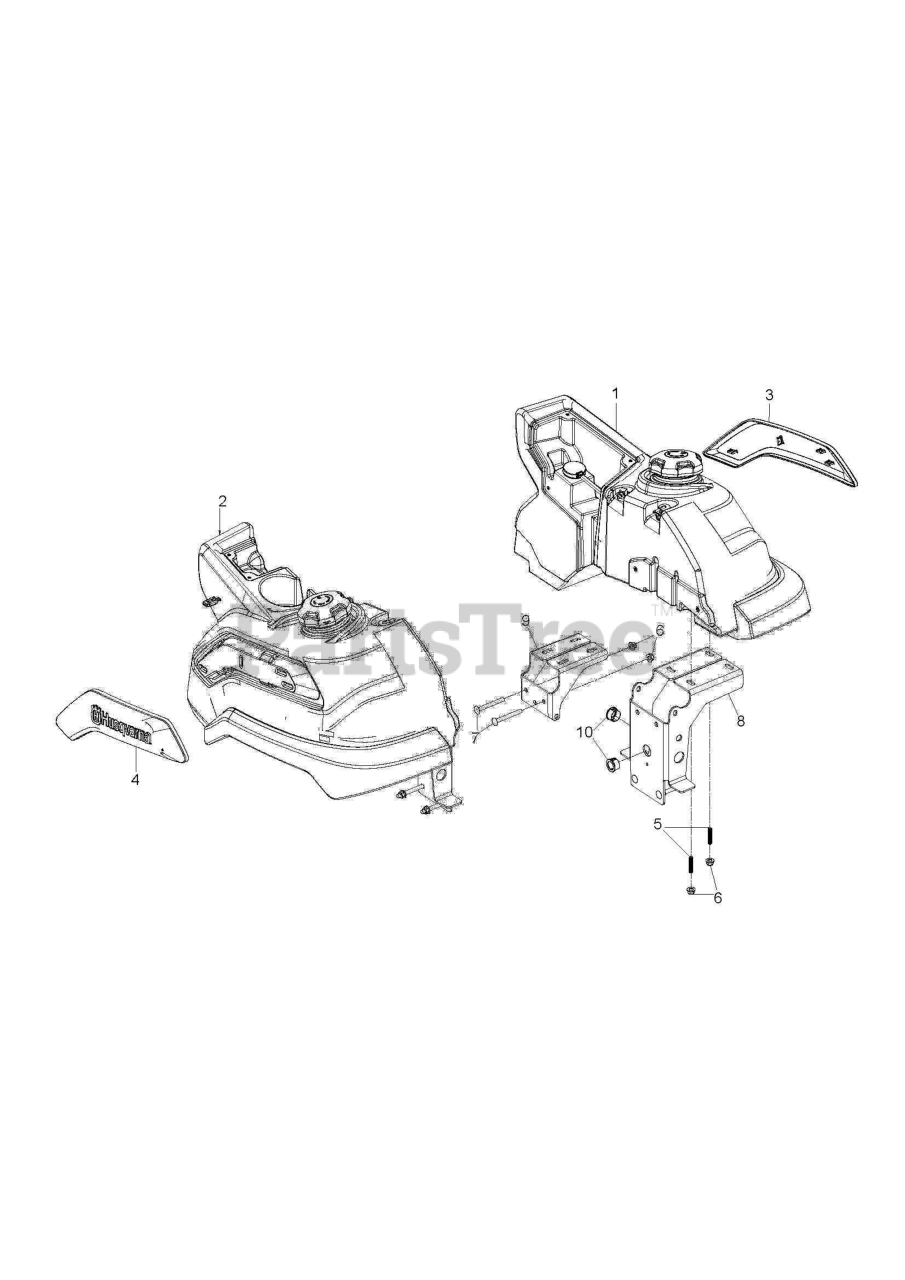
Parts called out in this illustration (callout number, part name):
3	COVER.RH.FUEL.TANK/CONSOLE APP
4	COVER.LH.FUEL.TANK/CONSOLE APP
5	SCREW.5/16-18X1.25"THREADED
6	NUT HEXAGON FLANGE 5/16-18 ST
7	Bolt, Carriage 5/16-18 x 2 - 3/4
